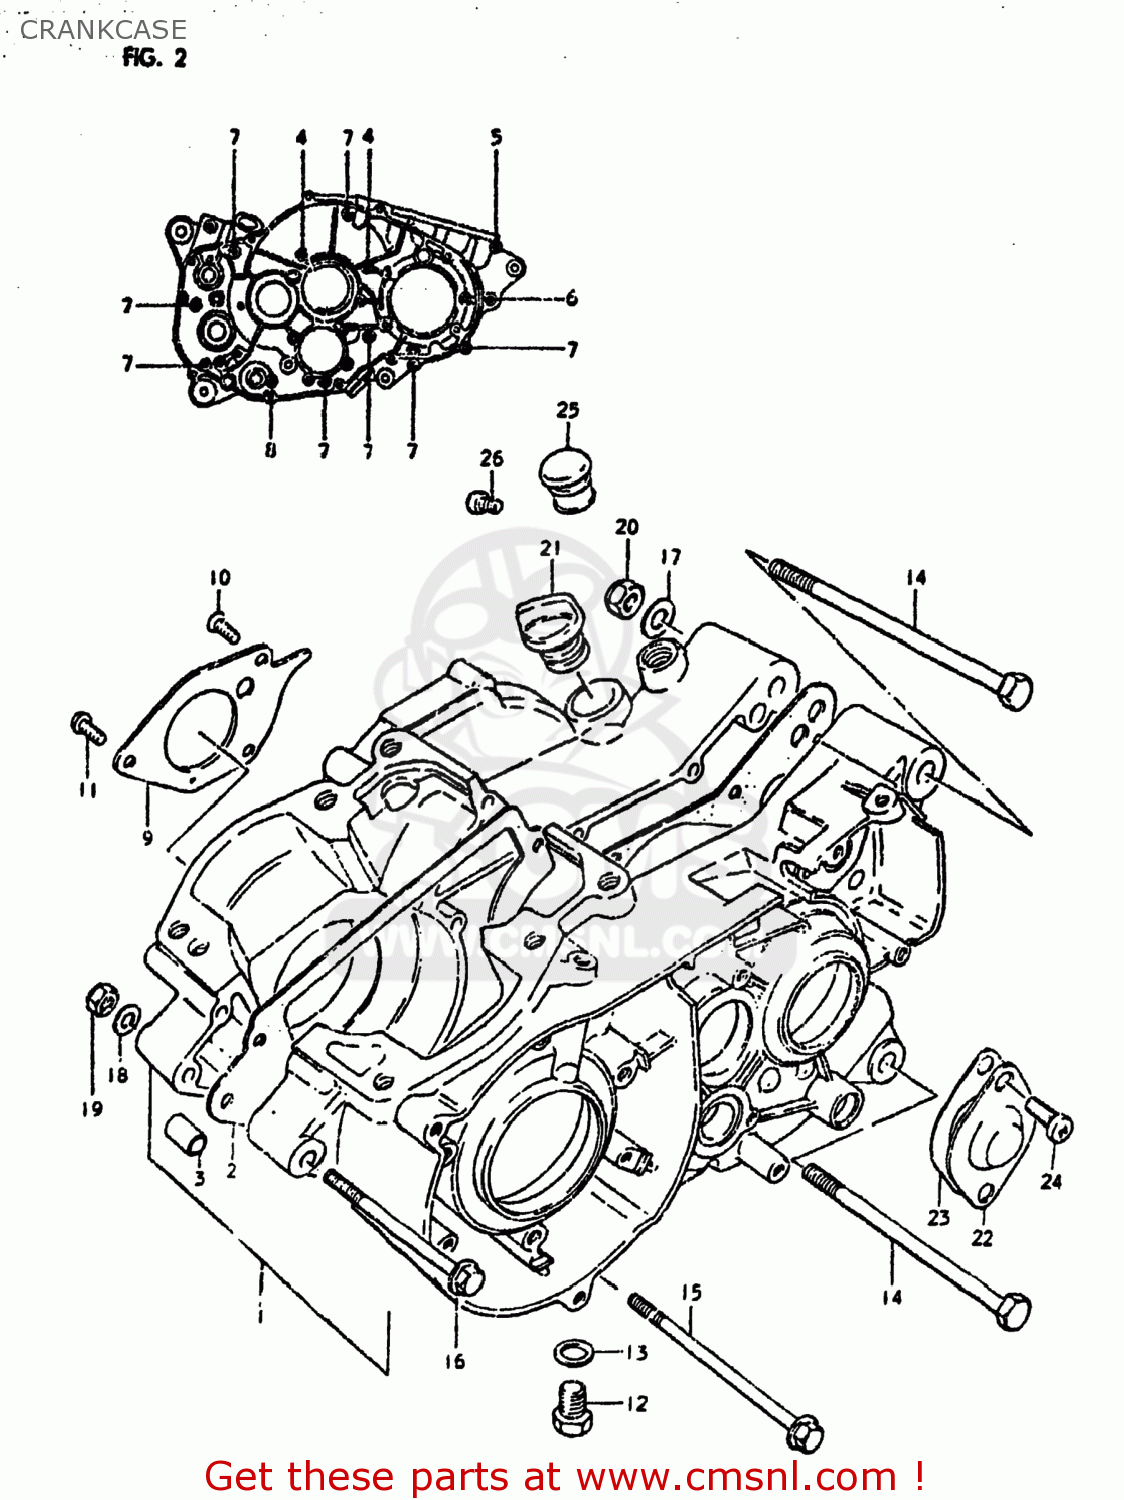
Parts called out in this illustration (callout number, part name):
1	CRANKCASE SET
2	GASKET,CRANKCASE (MCA)
3	PIN
4	SCREW
5	SCREW 6X65
6	SCREW
7	SCREW (6X45)
8	SCREW (6X35)
9	PLATE,OIL RESERVOIR
10	SCREW
11	SCREW
12	PLUG
13	GASKET(14X19.2X2) (NAS)
14	BOLT
15	BOLT
16	BOLT
17	WASHER
18	WASHER
19	NUT
20	NUT
21	PLUG
22	CAP,CAM PIVOT
23	GASKET (MCA)
24	SCREW
25	Plug
26	SCREW,6X6
